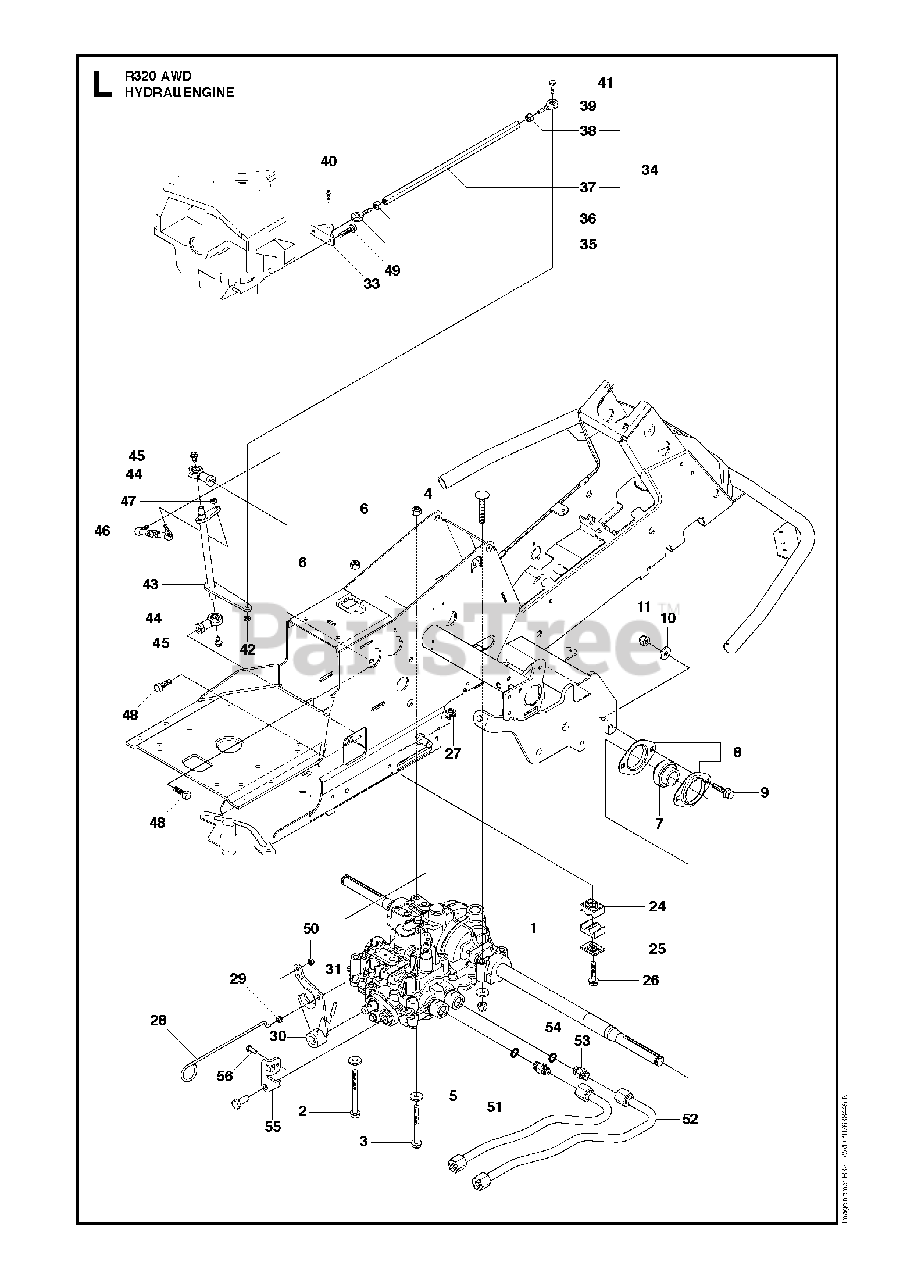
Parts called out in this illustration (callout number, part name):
1	TRANSMISSION SWE
5	WASHER BRB 8.4X17
6	LOCKNUT M8
8	BEARING HOUSING
9	BOLT
10	WASHER BRB 8.4X17
11	LOCKNUT M8
24	PIPE CLAMP
25	COVER PLATE
26	SCREW EHHFM
29	FUEL TANK BUSHING
34	ROD
35	LINK
36	NUT
37	ROD
38	NUT
39	LINK
42	LOCKNUT M6
45	SCREW EHHFM
46	ADJUSTING ROD
47	LOCKNUT M6
48	Screw, M10 X 25
50	LOCKNUT M6
51	HYDRAULIC PIPE
52	HYDRAULIC PIPE
53	PIPE FITTING
56	Screw
